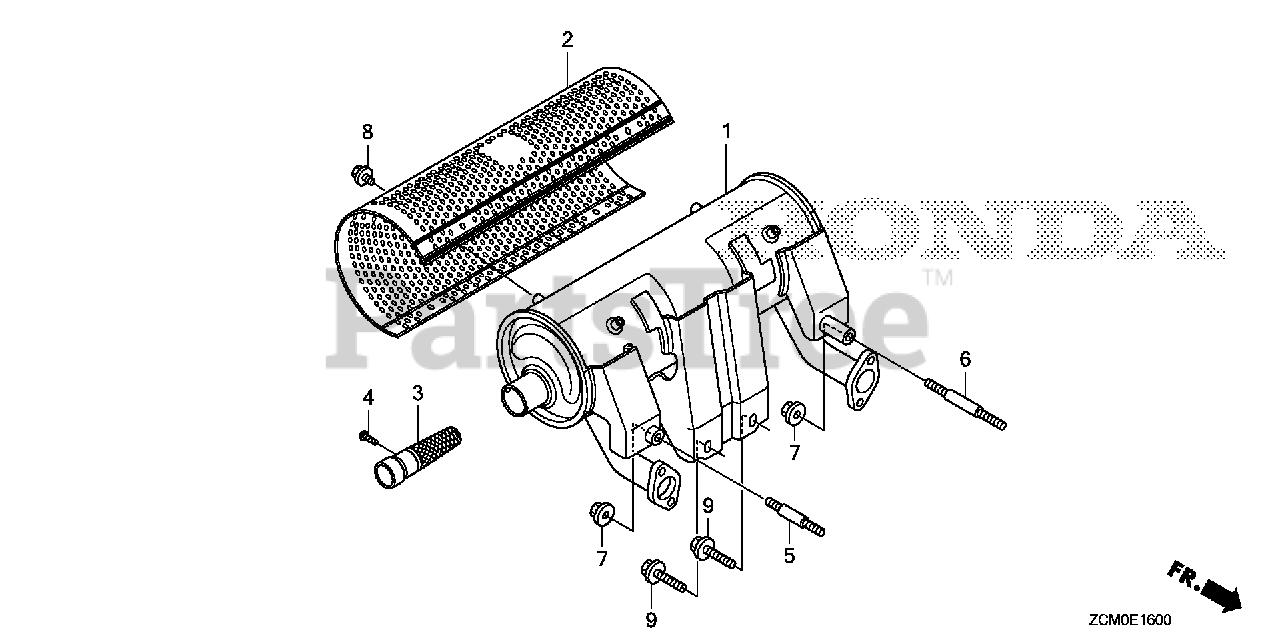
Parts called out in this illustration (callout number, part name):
1	MUFFLER (HIGH-R)
2	PROTECTOR, MUFFLER (HIGH) (FUTABA)
3	ARRESTER, SPARK
4	SCREW, TAPPING (5X8)
5	BOLT, STUD (8X45)
6	BOLT, STUD (8X60)
7	NUT, FLANGE (8MM)
8	BOLT, FLANGE (6X8)
9	BOLT, FLANGE (8X20)
